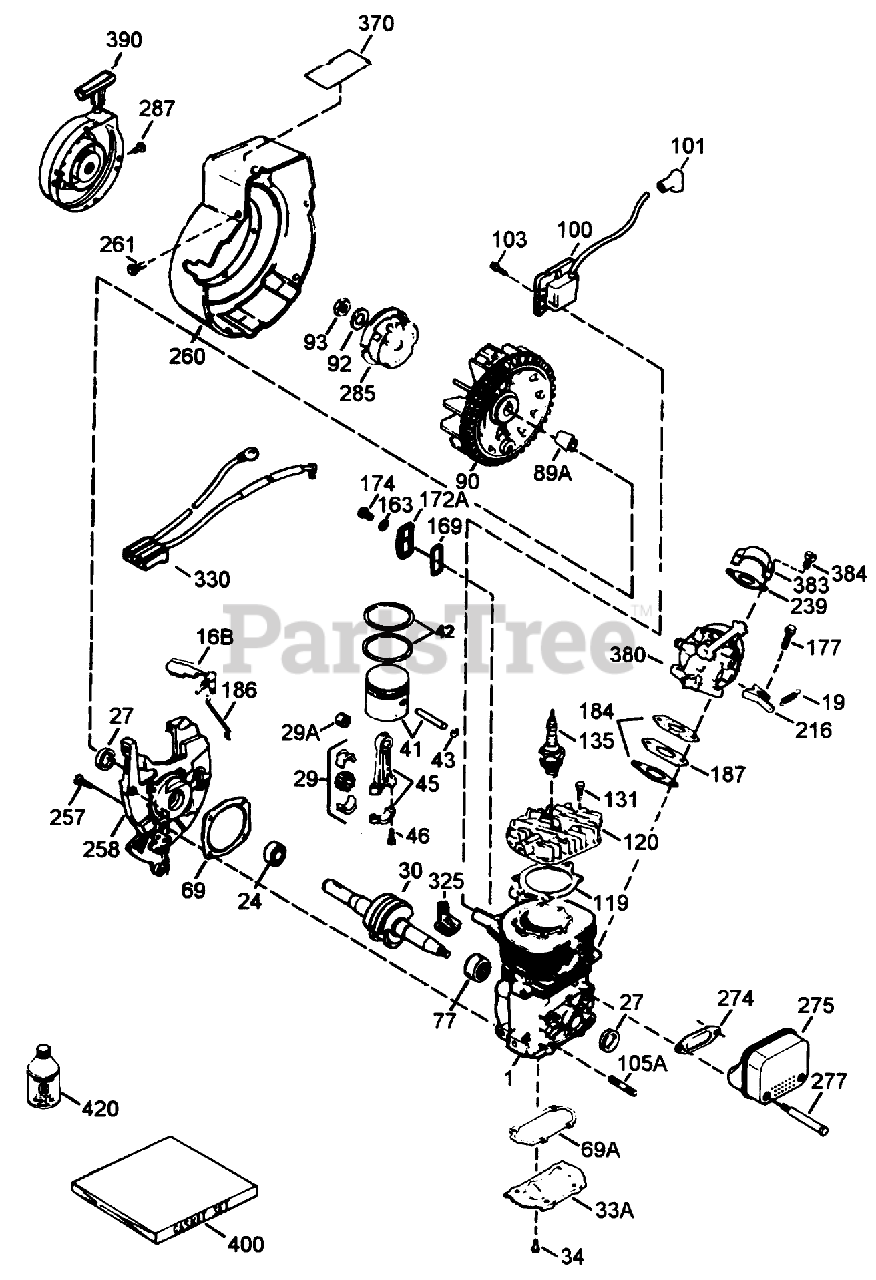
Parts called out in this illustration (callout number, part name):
1	Cylinder (Order Short Block if Replacement is Needed)
16B	Vane-Air
19	Spring-Extention
24	Bearing-Ball
27	Seal-Oil
29	Needle Bearing and Liner Set (37 Needles)
29A	Bearing-Cartridge
30	Crankshaft
33A	Plate-Cover
34	Screw (T-25, 10-24 x 1/2)
41	Piston (Incl. Ref. #43)
42	Ring Set
43	Ring-Retaning
45	Rod Assy.-Connecting (Incl. Ref. #3, 3A 3B)
46	Bolt-Rod, Connecting
69	Gasket-Cover, Cylinder
69A	Gasket-Plate, Cover
77	Cartridge Bearing
89	Blade (20 inch)
90	CARB BODY S
92	Washer-Belleville
93	Nut-Flywheel
100	Solid State
101	Cover-Spark Plug
103	Screw
119	Gasket-Head, Cylinder
120	Head-Cylinder
131	Screw (T-30, 1/4-20 x 3/4)
135	Spark Plug-Resistor (R C J 8Y)
163	Washer
169	Cover-Compression, Release
172A	Cover-Release, Compression
174	Screw (T-25, 10-24 x 1/2)
177	Screw (5/32 Allen, 1/4-20 x 1)
184	Gasket-Carburetor
186	Governor-Link
187	Spacer
216	Lever-Adjusting, Rpm
239	2060A77 WIZARD ROTA
257	Screw (T-30, 1/4-20 x 5/8)
258	Base Ass-y-Blower Housing (Incl Ref. #20)
260	Housing-Blower
261	Screw (1/4-20 x 1/2)
274	Exhaust Gasket
275	Muffler (Incl. Ref. #274 277)
277	Screw (1/4-20 x 2-3/4)
285	Cup-Starter
287	Screw (8-32 x 21/64)
325	Clip-Wire
330	Harness-Wire
370	Decal-Warning
380	Carburetor (Incl. Ref. #184A)
383	Baffle-Carburetor
384	Screw
390	Rewind Starter
390	Rewind Starter NOTE: This engine could have been built with a 590735 starter. Refer to the design of the air intake louvers for part identification. Individual starter parts do not interchange.
400	Gasket Set
420	2-Cycle Oil (8oz)
